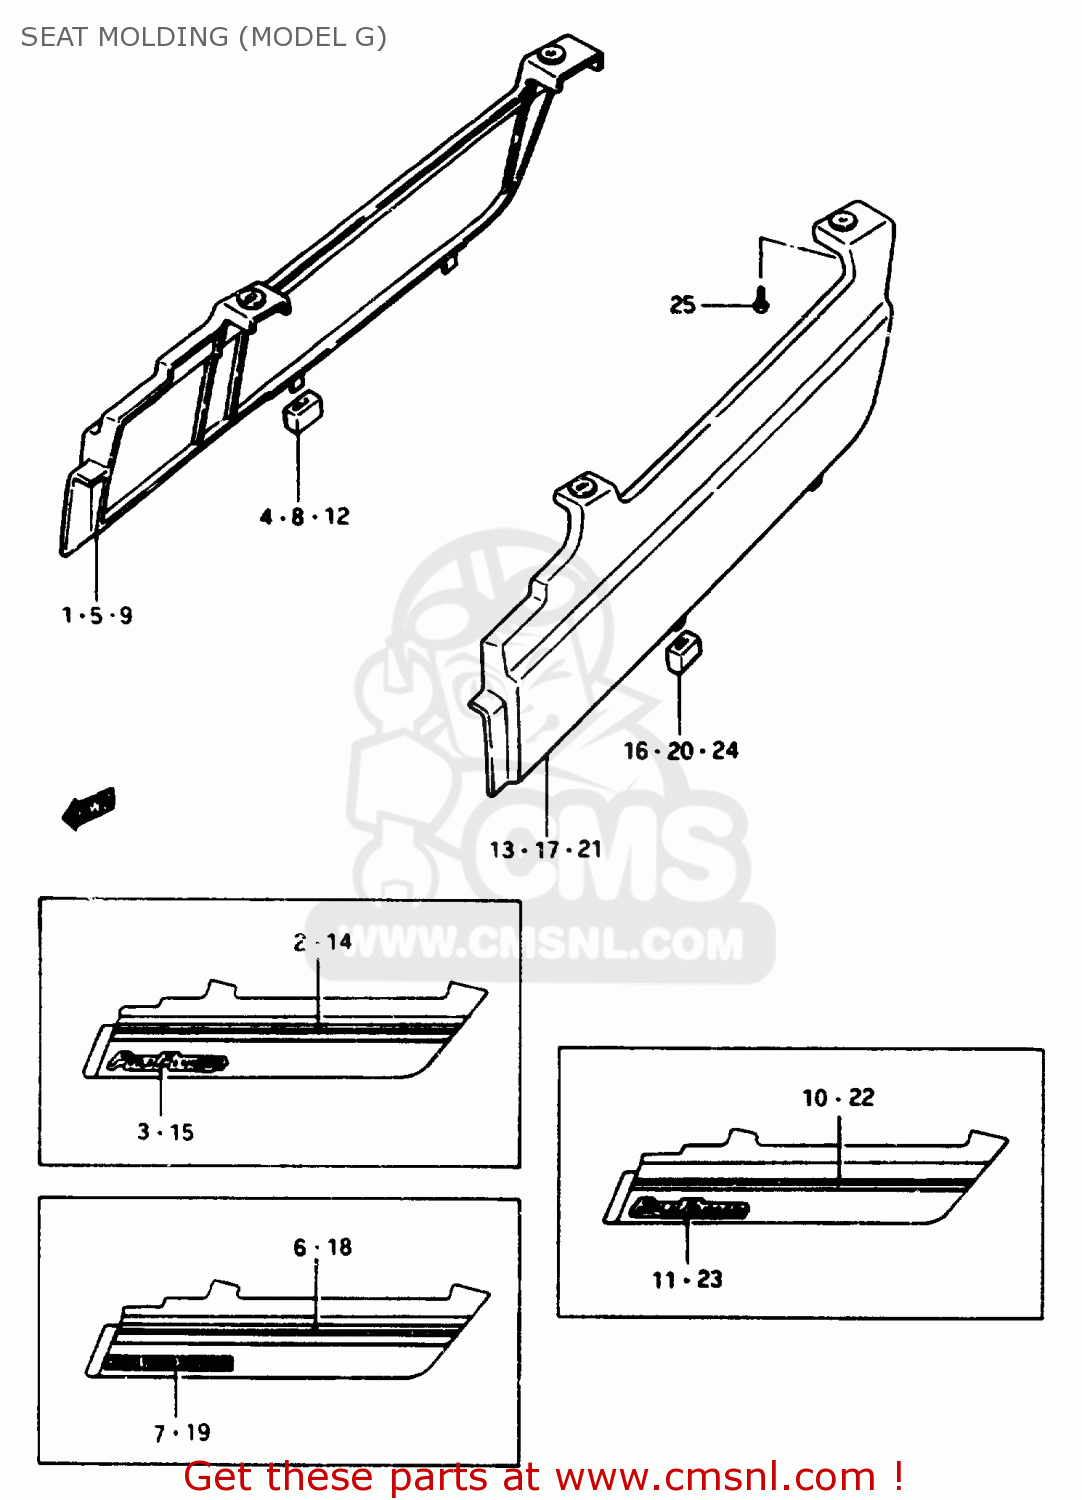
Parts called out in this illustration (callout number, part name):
1	MOLDING, SEAT RH
2	TAPE SET, RH
3	EMBLEM, FULL FLOATER
4	CAP,SEAT,MOLDING
5	MOLDING, SEAT RH
6	TAPE SET, RH
7	EMBLEM
8	CAP,SEAT,MOLDING
9	MOLDING, SEAT RH
10	TAPE SET,SEAT MOULDING
11	EMBLEM, FULL FLOATER
12	CAP,SEAT,MOLDING
13	MOLDING, SEAT LH
14	TAPE SET, LH
15	EMBLEM, FULL FLOATER
16	CAP,SEAT,MOLDING
17	MOLDING, SEAT LH
18	TAPE SET, LH
19	EMBLEM
20	CAP,SEAT,MOLDING
21	MOLDING, SEAT LH
22	TAPE SET
23	EMBLEM, FULL FLOATER
24	CAP,SEAT,MOLDING
25	SCREW
